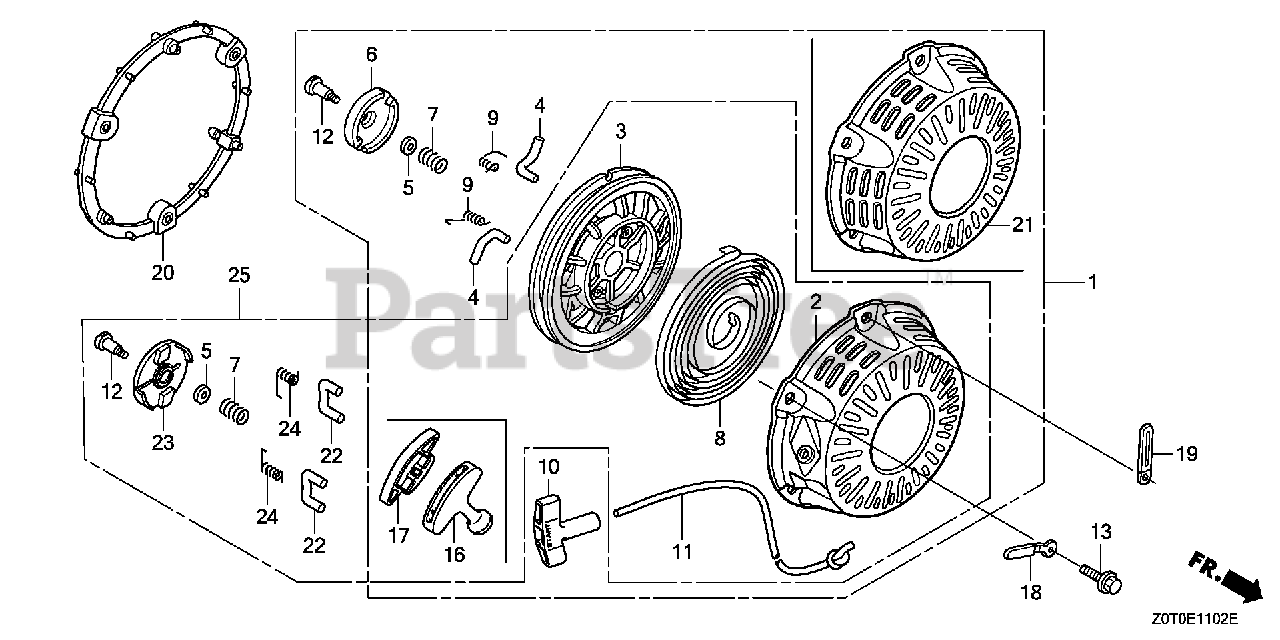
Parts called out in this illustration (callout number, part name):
1	STARTER ASSY., RECOIL *NH1* (BLACK)
1	STARTER ASSY., RECOIL *R280* (POWER RED)
2	CASE, RECOIL STARTER *R280* (POWER RED)
2	CASE, RECOIL STARTER *NH1* (BLACK)
3	REEL, RECOIL STARTER (BLACK)
4	RATCHET, STARTER
5	PLATE, FRICTION
6	GUIDE, RATCHET
7	SPRING, FRICTION
8	SPRING, RECOIL STARTER
9	SPRING, RETURN
10	GRIP, STARTER
10	KNOB, RECOIL SRARTER
11	ROPE, RECOIL STARTER
12	SCREW, SETTING
13	BOLT, FLANGE (6X10)
